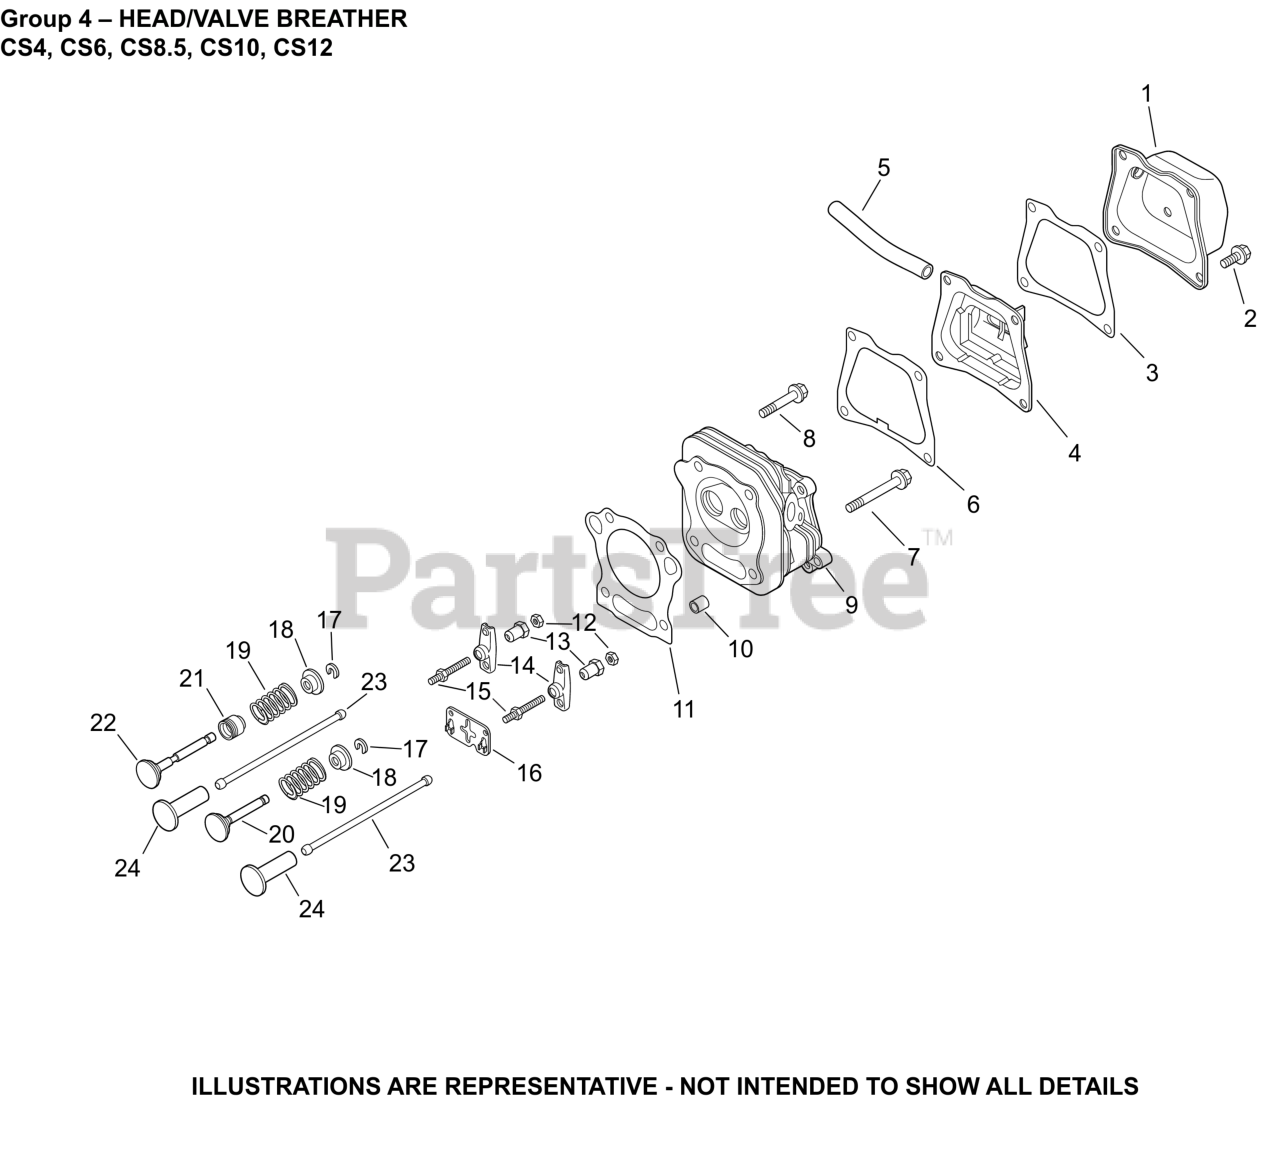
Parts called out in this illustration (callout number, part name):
1	COVER, VALVE
3	GASKET, VALVE COVER
4	BREATHER ASSEMBLY
5	HOSE, BREATHER
6	GASKET, BREATHER
7	SCREW, CYL HEAD
8	SCREW, CYL HEAD
9	CYLINDER HEAD
10	PIN, DOWEL
11	GASKET, CYLINDER HEAD
13	PIVOT, ROCKER ARM
14	ARM, ROCKER-(#DSC)
15	SCREW, VALVE ADJ
16	GUIDE, PUSH ROD
17	VALVE, COTTER
18	CAP,VALVE SPRING
19	SPRING, VALVE
20	VALVE, INTAKE
21	SEAL, VALVE STEM
22	VALVE, EXHAUST
24	LIFTER, VALVE
